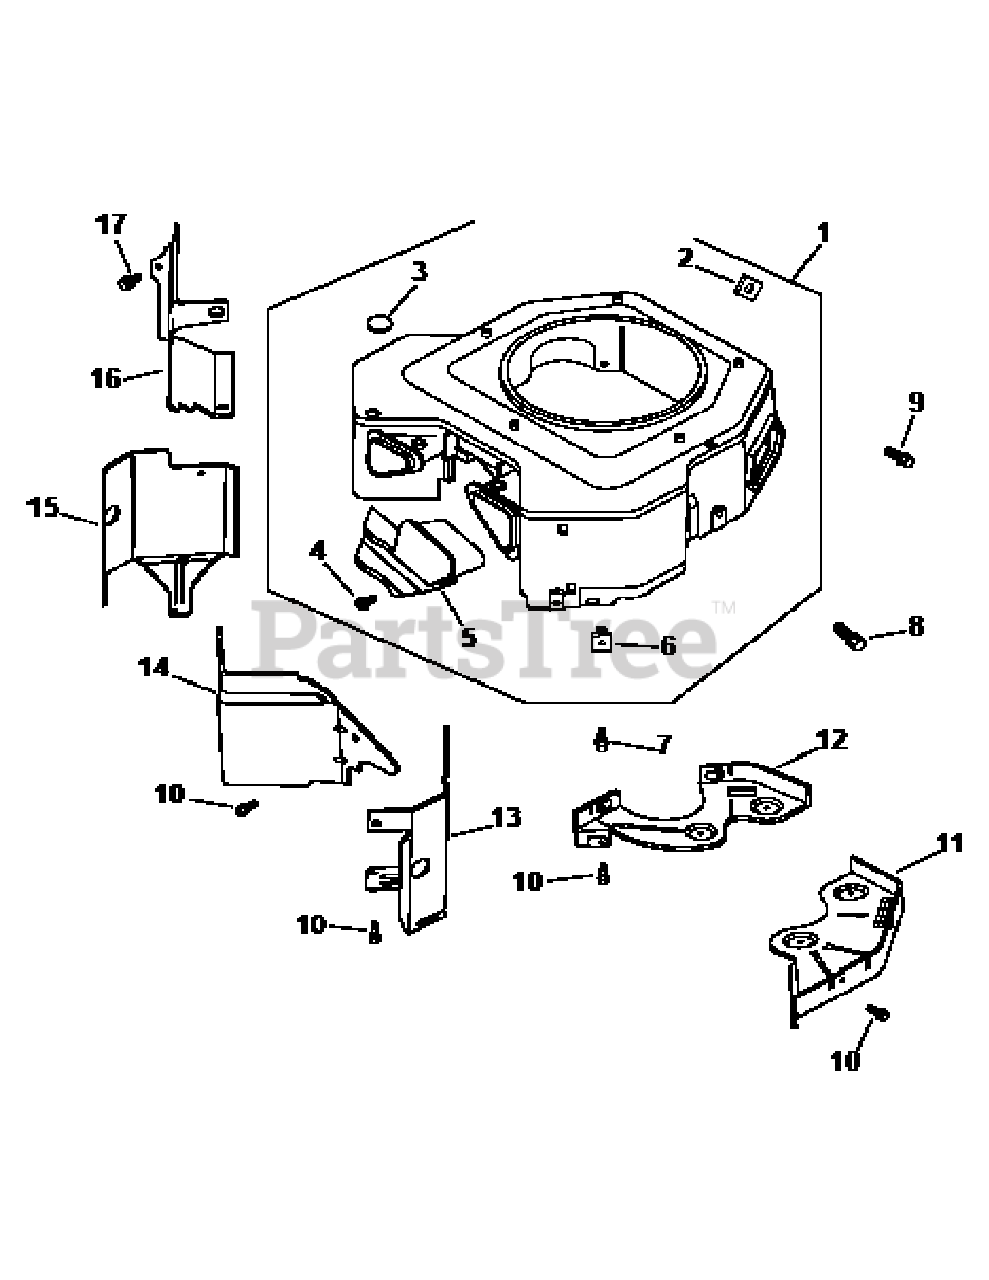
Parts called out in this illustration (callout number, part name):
1	Blower Housing
2	Plastic Nut
3	9/16" Button Plug
4	Tapping Screw
5	Blower Housing Cover
7	Screw
9	Screw
11	Backing Plate # 2 Side
12	Backing Plate # 1 Side
13	Cylinder Barrel Baffle # 2 Side
14	Valley Baffle # 2 Side
15	Cylinder Barrel Baffle # 1 Side
16	Valley Baffle # 1 Side
